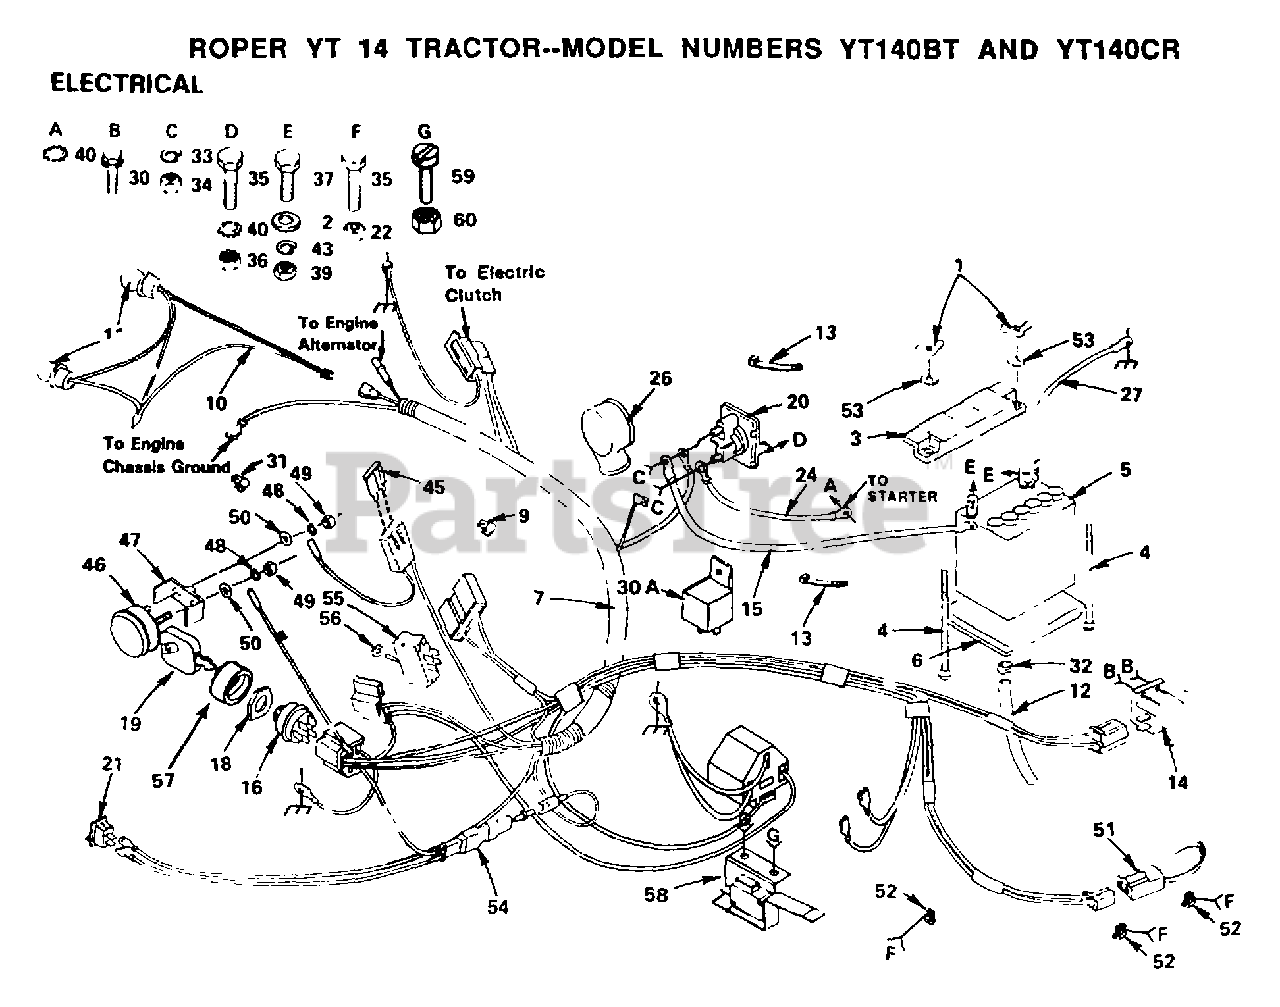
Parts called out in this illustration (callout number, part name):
2	WASHER
4	BOLT
6	"TRAY T, BATTERY"
10	HARNESS T
13	WIRE TIE
14	SWITCH-INTER. GT
15	CABLE-BATTERY T
21	SWITCH LT
27	CABLE T
30	SCREW
30A	RELAY ASSY T
31	CLIP T
32	HOSE CLAMP T
34	NUT
35	BOLT
36	NUT
37	BOLT LT
43	LOCKWASHER
45	FUSE HYT
46	AMMETER T
50	WASHER
52	CLIPT
53	LOCKWASHER GT
55	SWITCH.PTO.T
56	HEX NUT T
60	"NUT,KEPS"
